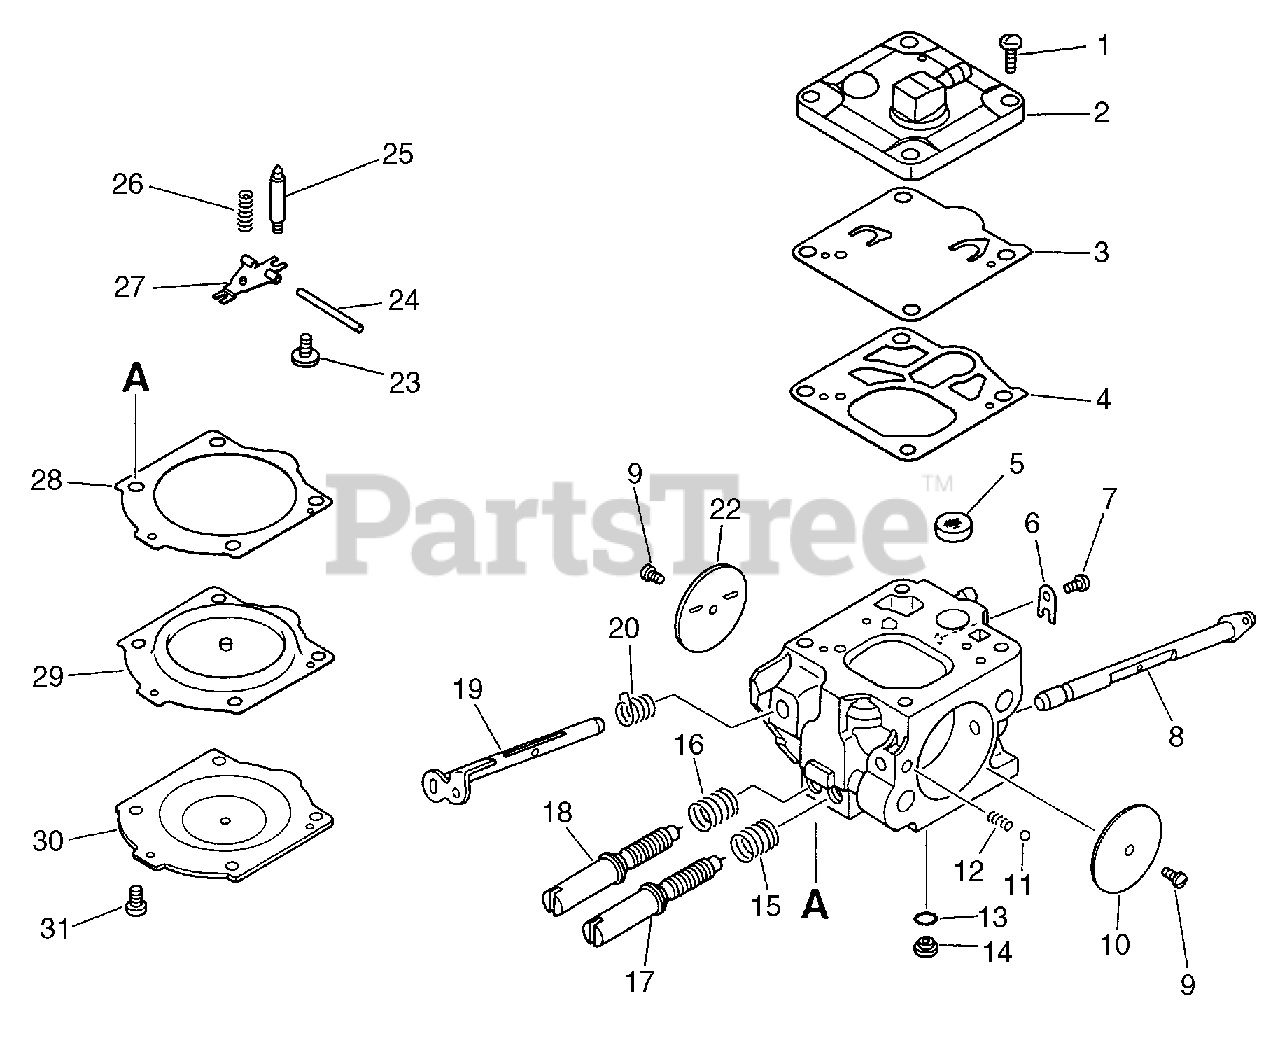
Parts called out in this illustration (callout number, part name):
1	SCREW
2	COVER, PUMP
3	GASKET, PUMP
4	DIAPHRAGM, PUMP
5	STRAINER
6	RING, RETAINING
7	SCREW
8	SHAFT, CHOKE
9	SCREW
10	VALVE, CHOKE
11	BALL, CHOKE SET
12	SPRING, CHOKE SET
13	PLUG, WELCH - LARGE
14	VALVE, CHECK
15	SPRING
16	SPRING
17	NEEDLE - HIGH SPEED
18	NEEDLE - LOW SPEED
19	SHAFT, THROTTLE
20	SPRING, RETURN
22	VALVE, THROTTLE
23	SCREW, METERING LEVER PIN
24	PIN, METERING LEVER
25	VALVE, INLET NEEDLE
26	SPRING, METERING LEVER
27	LEVER, METERING
28	GASKET, DIAPHRAGM
29	DIAPHRAGM
30	COVER, DIAPHRAGM
31	SCREW
